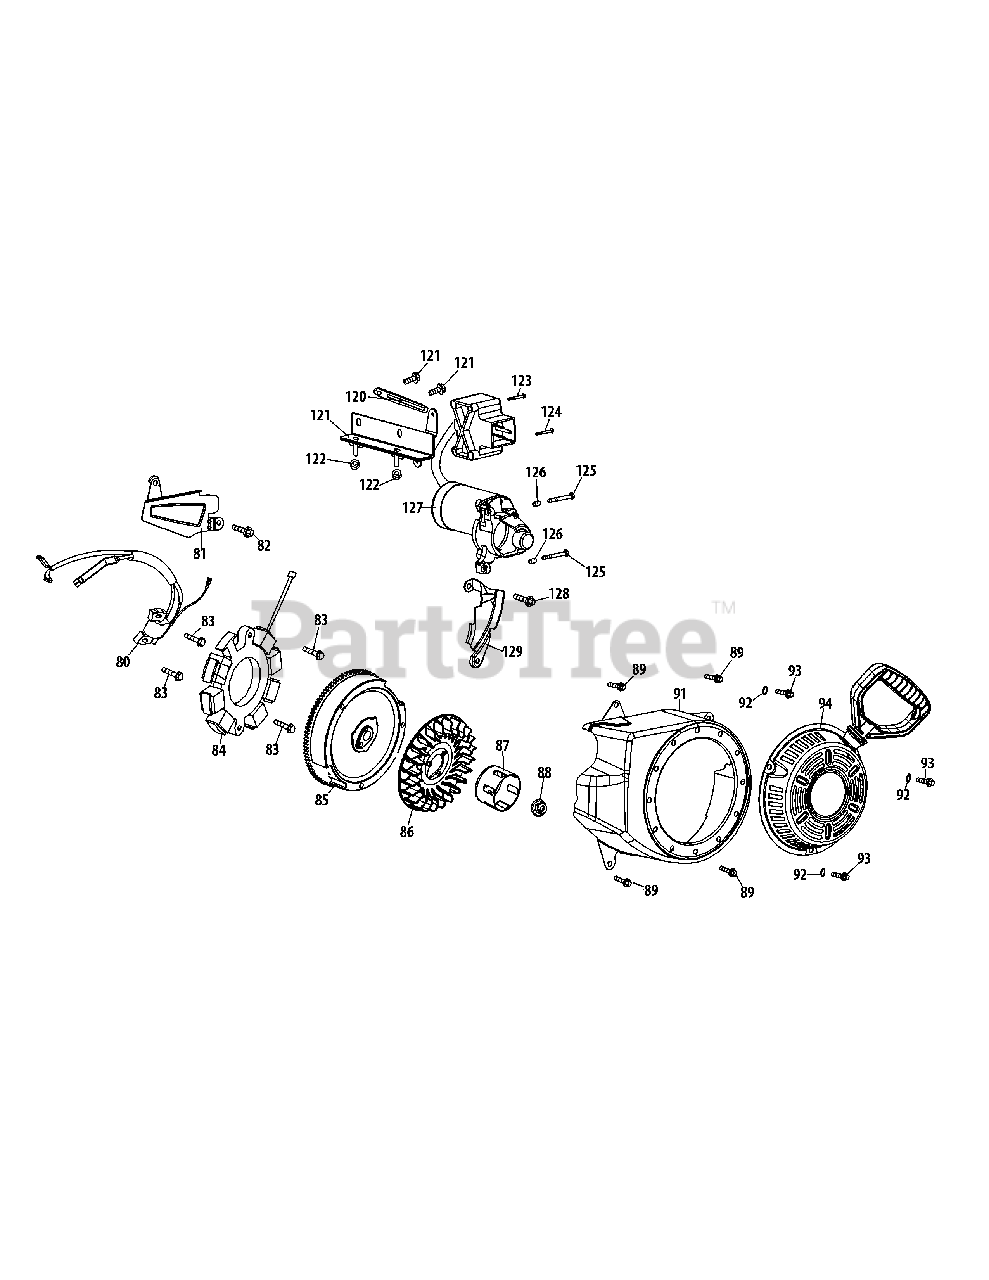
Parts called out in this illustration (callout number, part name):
80	Ignition Coil Assembly
81	Air Flow Shield
82	Bolt M6×10
83	Bolt M6×25
84	Alternator Assembly
86	Cooling Fan
87	Starter Cup
88	Flywheel Nut, M14×1.5
89	Bolt M6×12
91	Blower Housing
92	Washer 6
93	Bolt M6×10
94	Recoil Starter Assembly
119	Bolt M6×10
120	Electric Starter Cord Retainer
121	Switch Housing Mounting Bracket
123	Bolt M4×55
124	Bolt M4×60
125	Bolt M6×32
126	Dowel Pin 8×8
127	Electric Starter
128	Bolt M6×12
129	Blower Housing Shield
